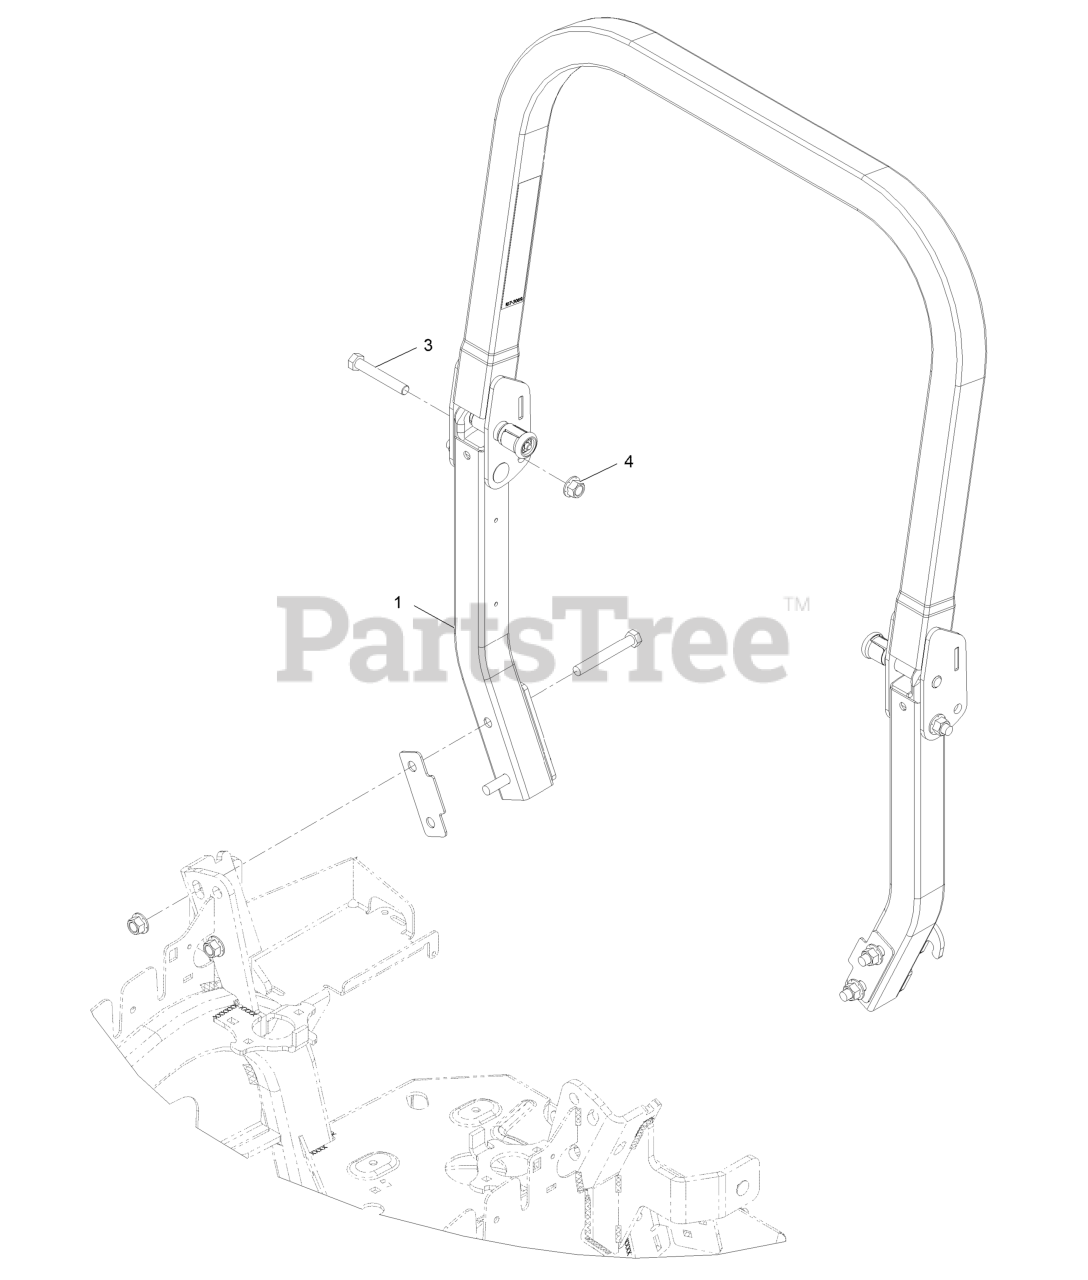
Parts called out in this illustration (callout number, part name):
1	ROPS ASM
3	SCREW-HH
4	Nut-Lock 1/2-13
